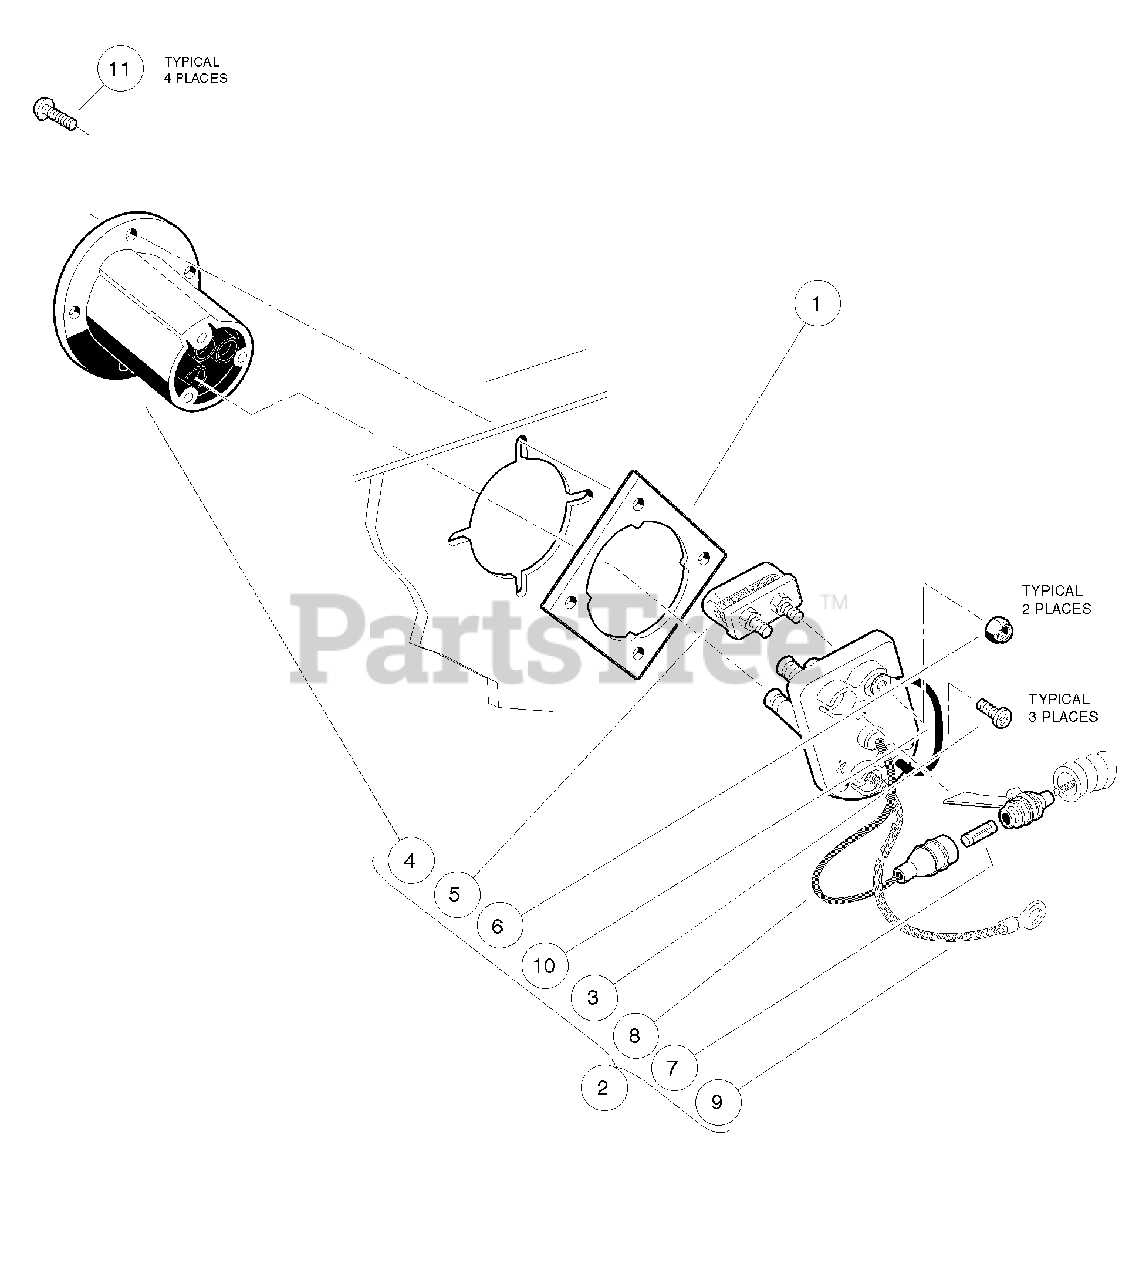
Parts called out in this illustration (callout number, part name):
1	Plate, Receptacle Backing
2	Fuse and Receptacle Assembly
3	Screw, #8 X 5/8 Phillips Pan-Head Type AB
4	Receptacle
5	Fuse Assembly
6	Locknut, #10-32 Nylon Insert
7	Fuse, 3/8-Amp
8	Wire Assembly, Sense Lead, Gray
9	Wire Assembly, #10 Red
10	Wire Assembly, #10 Black
11	Screw, #7-19 X 0.625 Phillips Pan-Head Tap
